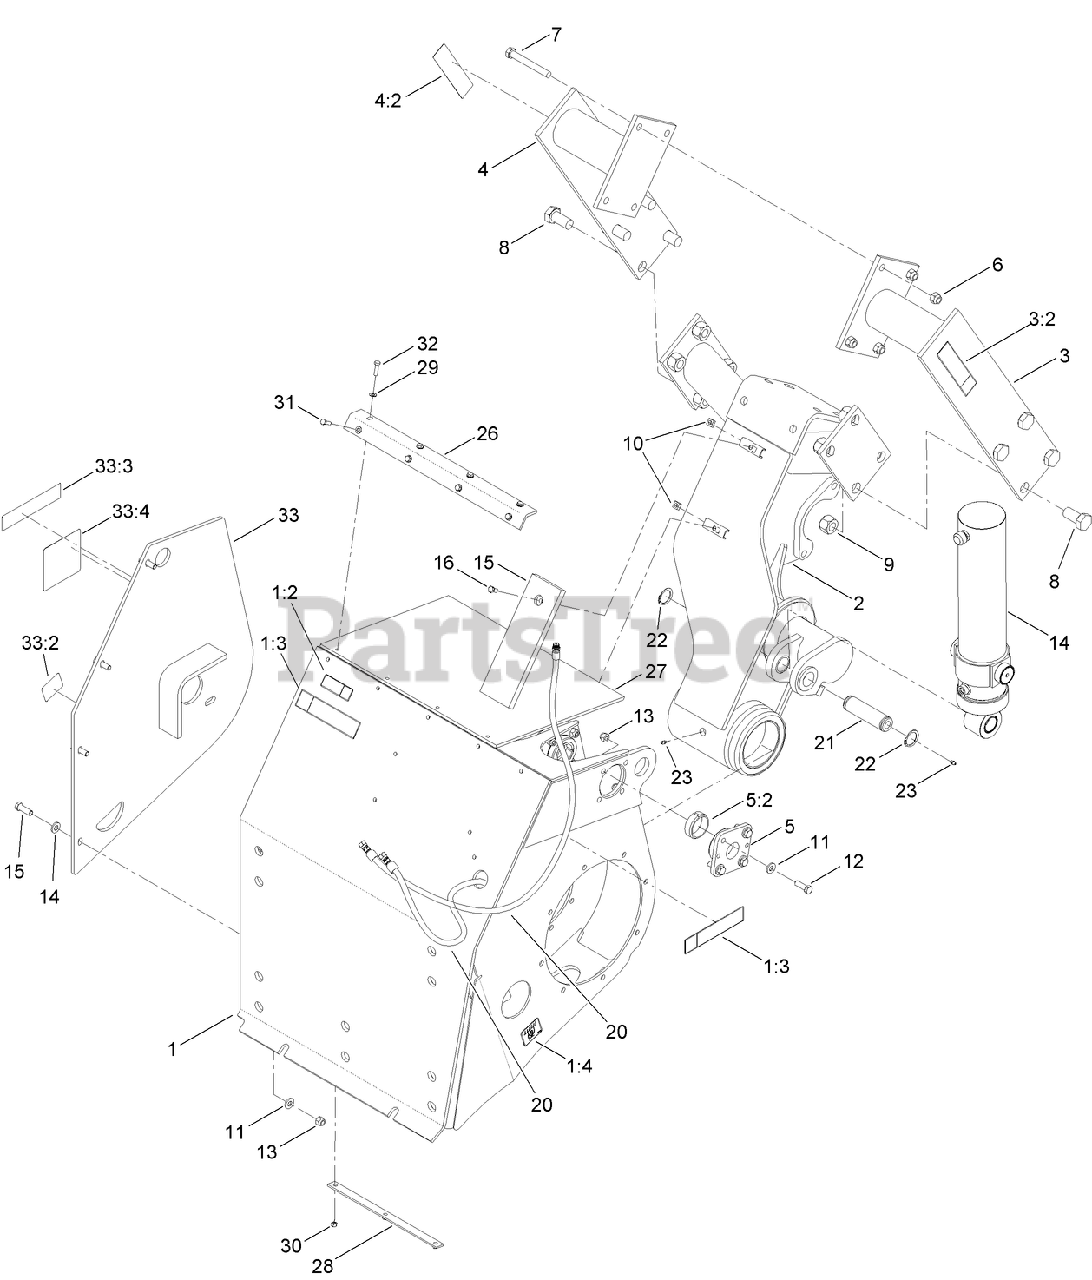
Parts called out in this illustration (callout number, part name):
1	TRENCHER FRAME ASM
1:2	DECAL-DANGER
1:3	DECAL-DANGER, ENTANGLEMENT
1:4	DECAL-TIE DOWN
2	BRACKET-MOUNT, BOOM ATTACH
3	LH CRUMBER MOUNTING ASM
3:2	DECAL-DANGER, ENTANGLEMENT
4	RH CRUMBER MOUNTING ASM
4:2	DECAL-DANGER, ENTANGLEMENT
5	PIVOT BLOCK ASM
5:2	BUSHING
6	NUT-LOCK, HEX
10	NUT-SQUARE
12	SCREW-HH
13	NUT-HEX
14	HYD CYLINDER ASM
15	STRIP-WEAR, LONG
16	SCREW-HH
20	HYD HOSE ASM, HP
21	PIN-PIVOT
23	FITTING-GREASE
26	ANGLE-MOUNTING, DIRT DEFLECTOR
27	DEFLECTOR-DIRT
28	STRIP-DIRT DEFLECTOR
29	WASHER
30	NUT-HEX
31	SCREW-HH
32	SCREW-HH
33	SUPPORT BEARING PLATE ASM
33:2	DECAL-TIE DOWN
33:3	DECAL-DANGER, ENTANGLEMENT
33:4	DECAL-TRANSMISSION FLUID
